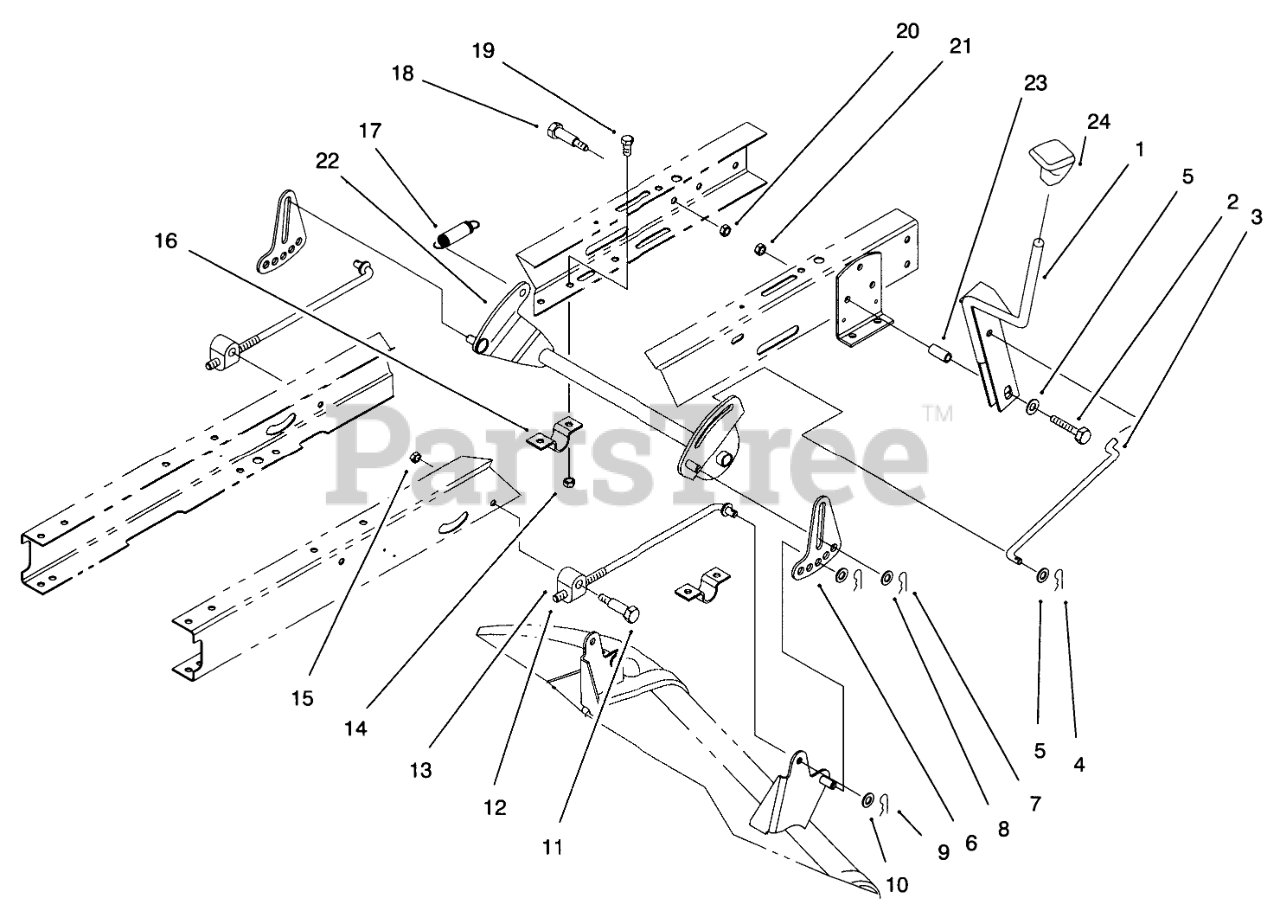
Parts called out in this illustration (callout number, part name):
1	HOC LEVER ASM
2	SCREW-HH
3	LINK-HOC
4	PIN-COTTER
5	WASHER-FLAT
6	LINK-ADJUSTING, HOC
7	PIN-COTTER
8	WASHER-HARDENED
9	PIN-COTTER
10	WASHER-FLAT
11	SCREW-SHOULDER, HH
12	ROD-HANGER, REAR
13	TRUNNION-HOC
14	NUT-LOCK, NI
15	NUT-LOCK, NI
16	CLAMP-PIVOT, HOC
17	SPRING-EXTENSION
18	SCREW-SHOULDER, HH
19	SCREW-HH
20	NUT-LOCK, NI
21	NUT-LOCK, NI
22	PIVOT ASM
23	SPACER
24	KNOB-SHIFT
